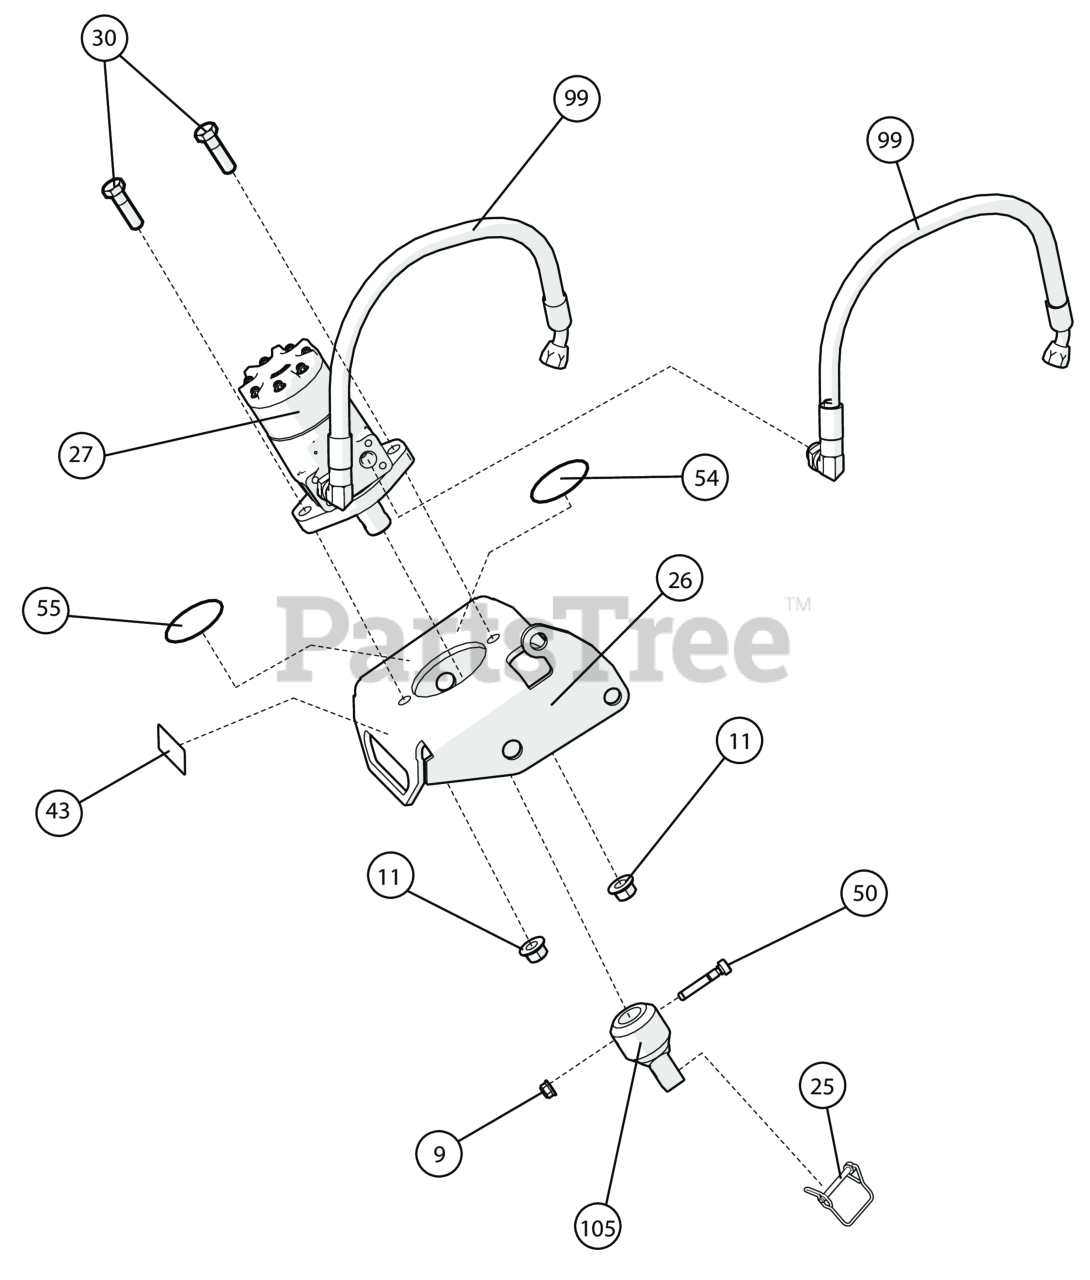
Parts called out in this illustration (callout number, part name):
9	NUT-HEX-NYLK, FLG .3125-18 ZP
11	NUT-HEX-NYLK, FLG .500"-13 ZP
25	LOCKING PIN, .25" OD X 3.00", ZP
26	WA, MOTOR PLATE
27	MOTOR, HYDRAULIC 306CC
30	SCREWCAP 1/2"-13 X 1 3/4" HCS ZP GR. 5
43	LABEL HOT SURFACE
50	BOLT SHOULDER 3/8" X 2"
54	DECAL, 811 WARNING
55	DECAL, AGR T2V
99	VALVE TO MOTOR HOSE 23" OAL
105	ADAPTER, HYDRAULIC MOTOR 7/8" SQUARE
